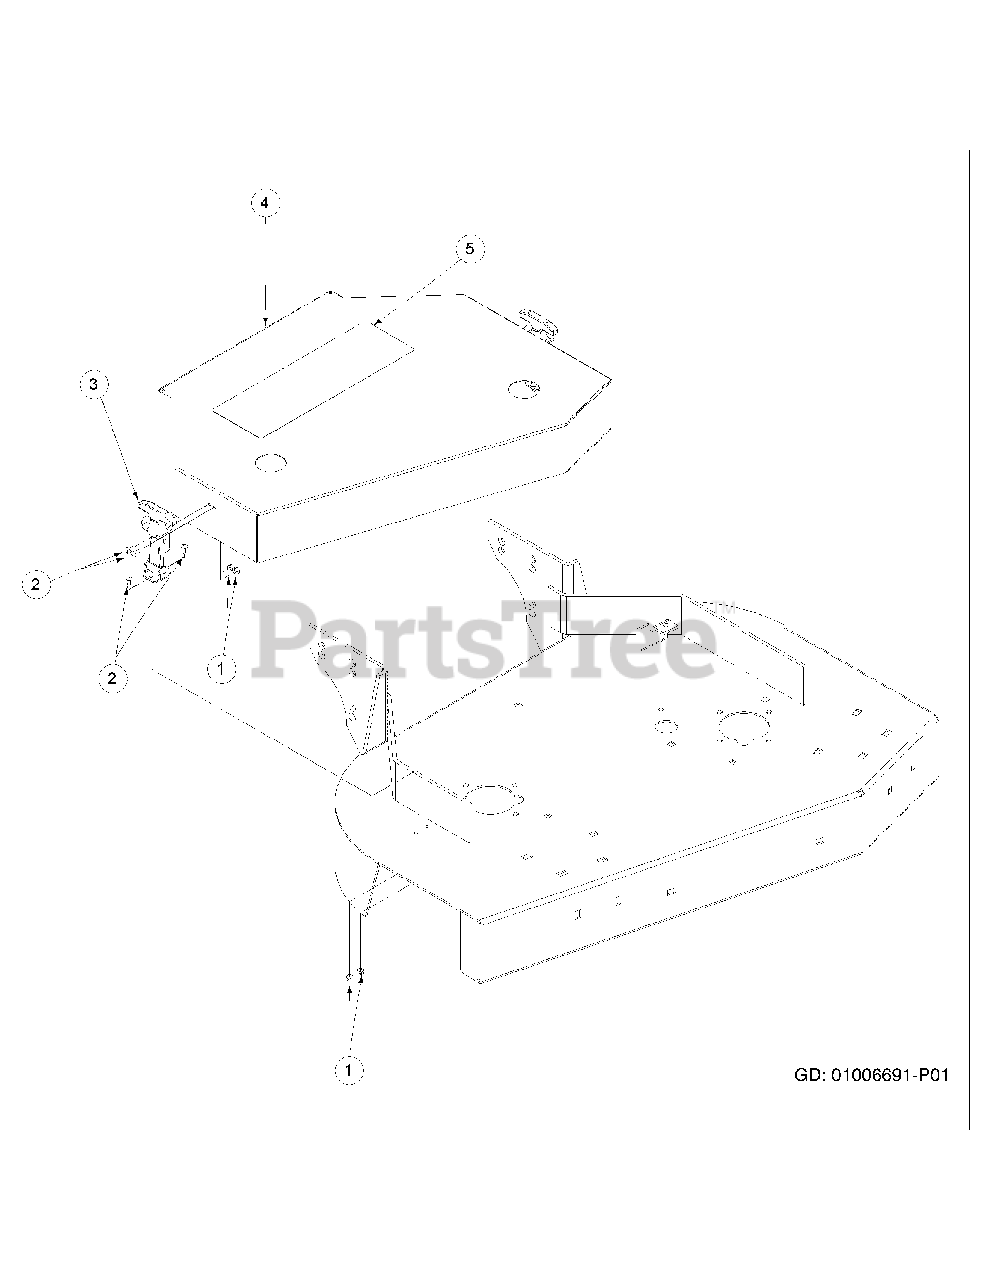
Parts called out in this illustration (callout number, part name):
1	Lock Nut, Nylon Insert #10-24
2	Machine Screw, 10-24 x 1/2
3	Rubber Hood Latch
4	Deck Cover, 36
5	Label Commercial Mower
6	Label, H1536
